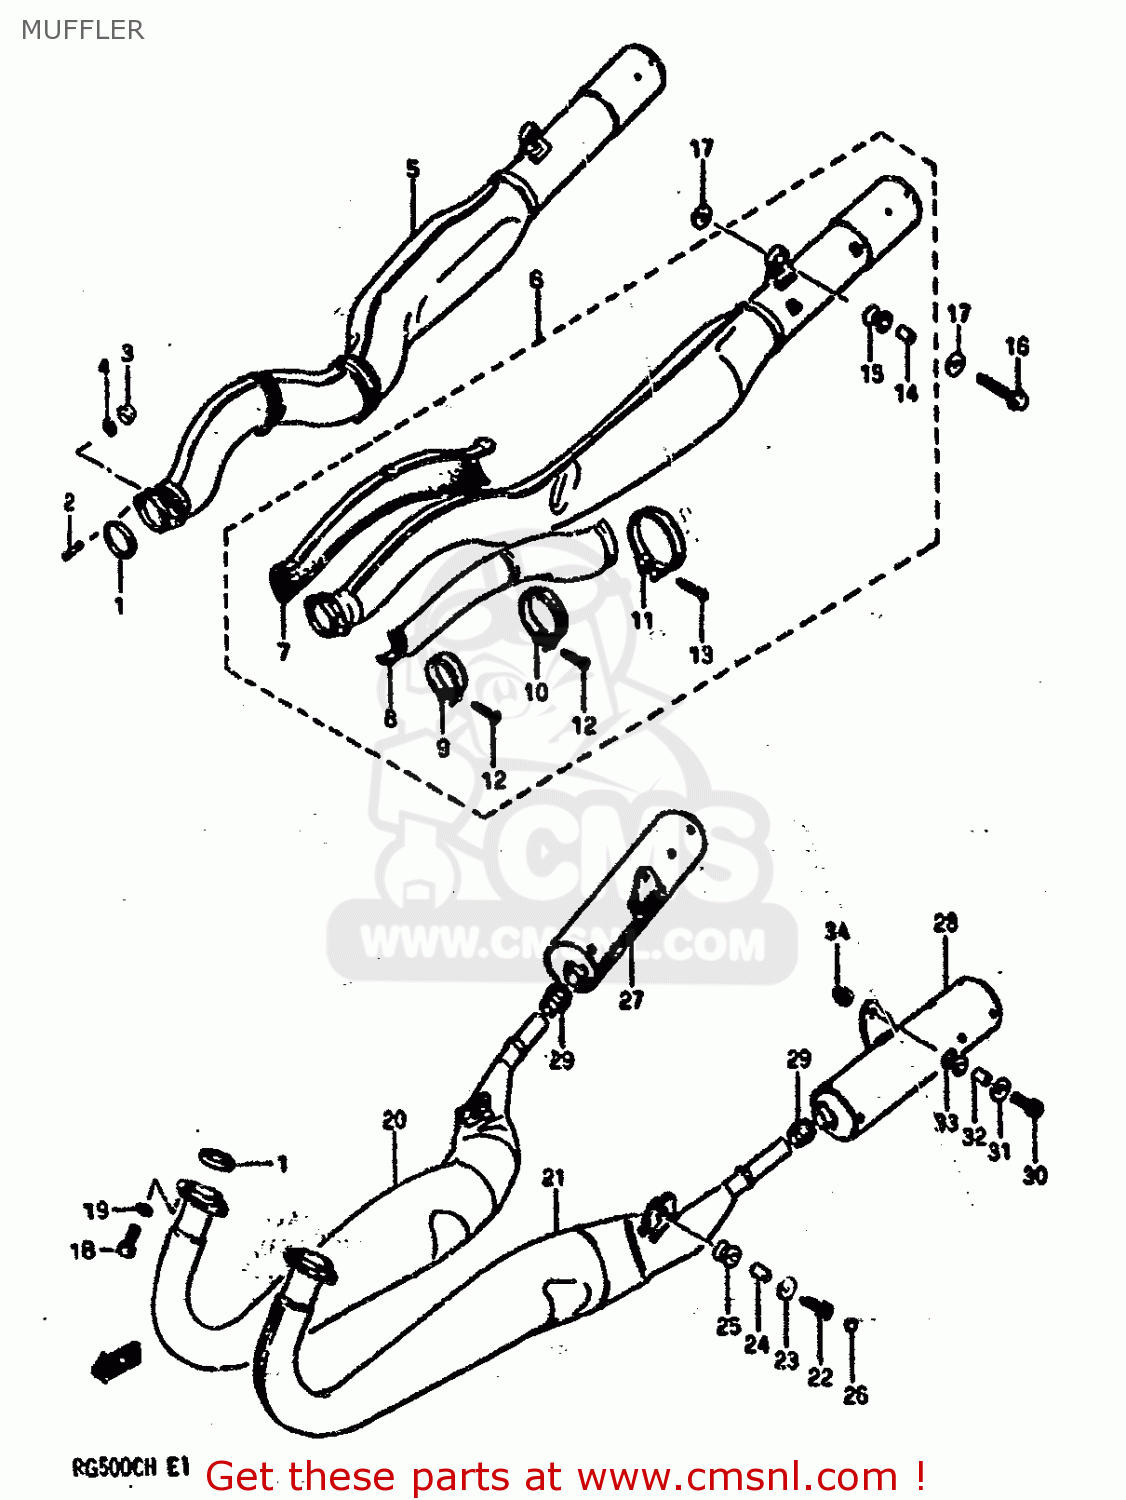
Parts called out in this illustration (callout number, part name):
1	GASKET,EXHAUST PIPE (NAS)
2	STUD BOLT
3	NUT 8MM
4	WASHER,LOCK,8.
5	MUFFLER ASSY,UPPER RH
6	MUFFLER ASSY,UPPER LH
7	COVER,MUFFLER UPPPER
8	COVER,MUFFLER 1ST UPR
9	CLAMP
10	CLAMP
11	CLAMP
12	SCREW
13	SCREW
14	SPACER (8.6X12X17.5)
15	CUSHION
16	BOLT (8X65)
17	WASHER (8.5X20X1.6)
18	BOLT
19	WASHER,LOCK,8.
20	MUFFLER,1ST UNDER RH
21	MUFFLER,1ST UNDER LH
22	BOLT, REAR (8X30)
23	WASHER (8.5X20X1.6)
24	SPACER (8.6X12X17.5)
25	CUSHION
26	CAP(OD:10)
27	BODY,MUFFLER 2ND RH
28	BODY,MUFFLER 2ND LH
29	CONNECTOR,MUFFLER
30	BOLT
31	WASHER
32	SPACER (8.6X12X17.5)
33	CUSHION
34	NUT,M8X1.25X12
